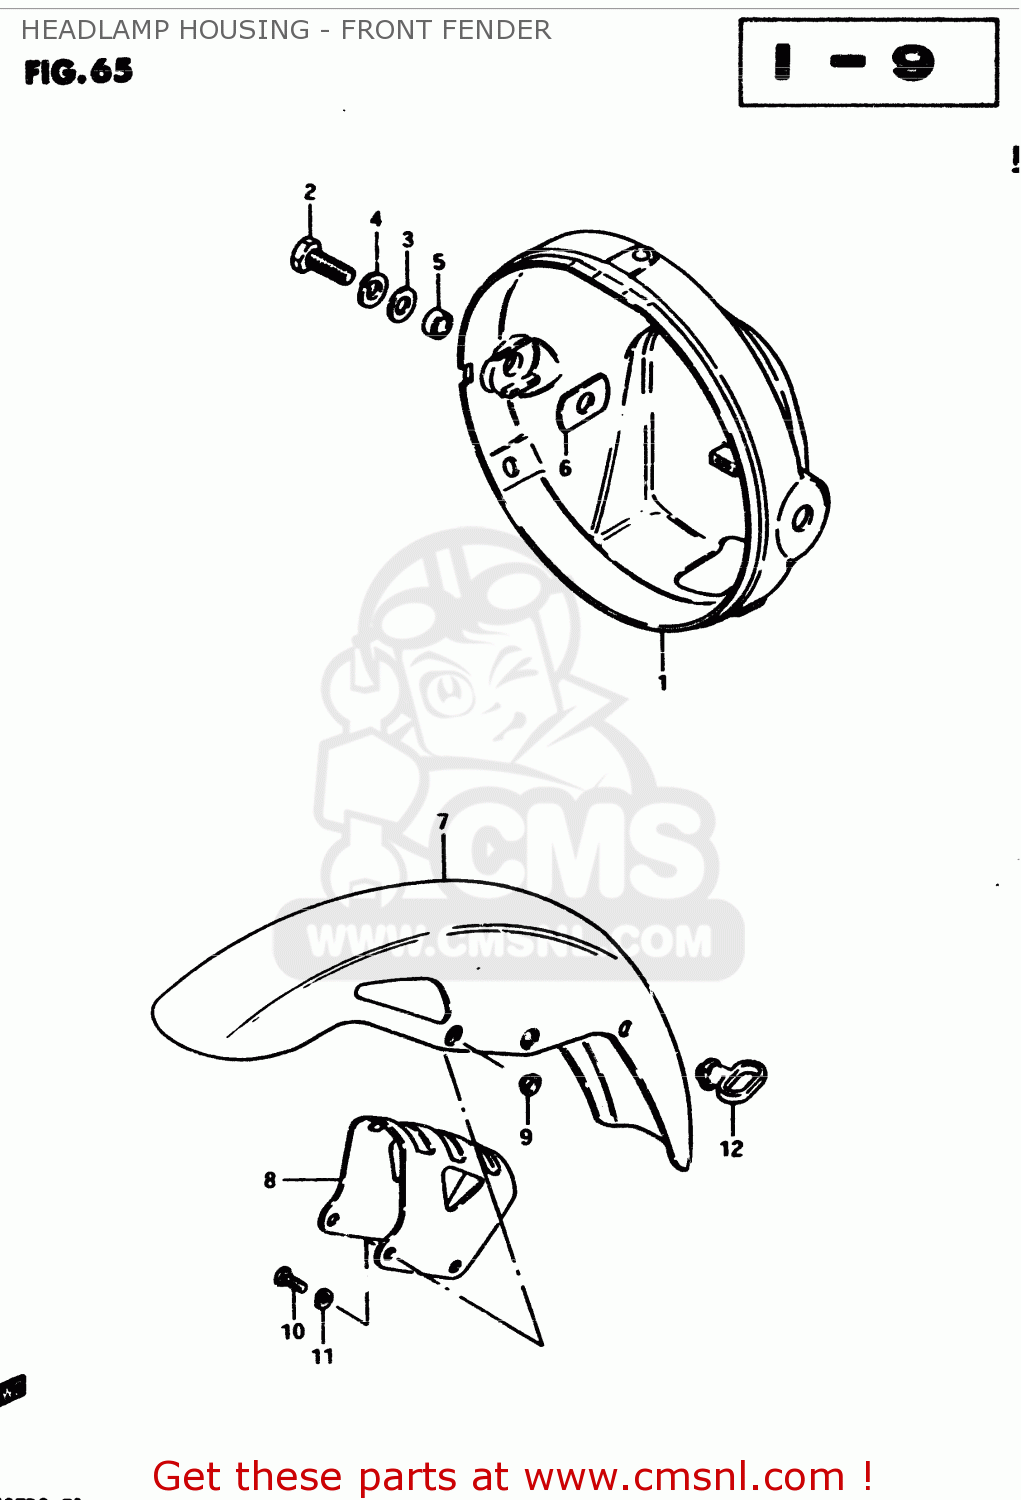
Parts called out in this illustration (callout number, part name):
1	HOUSING,HEADLAMP
2	BOLT
3	WASHER
4	LOCK WASHER
5	SPACER (8.8X12X7)
6	CUSHION
7	FENDER,FRONT
8	BRACE,FRONT FENDER
9	WASHER
10	BOLT
11	LOCK WASHER
12	GUIDE,CABLE
